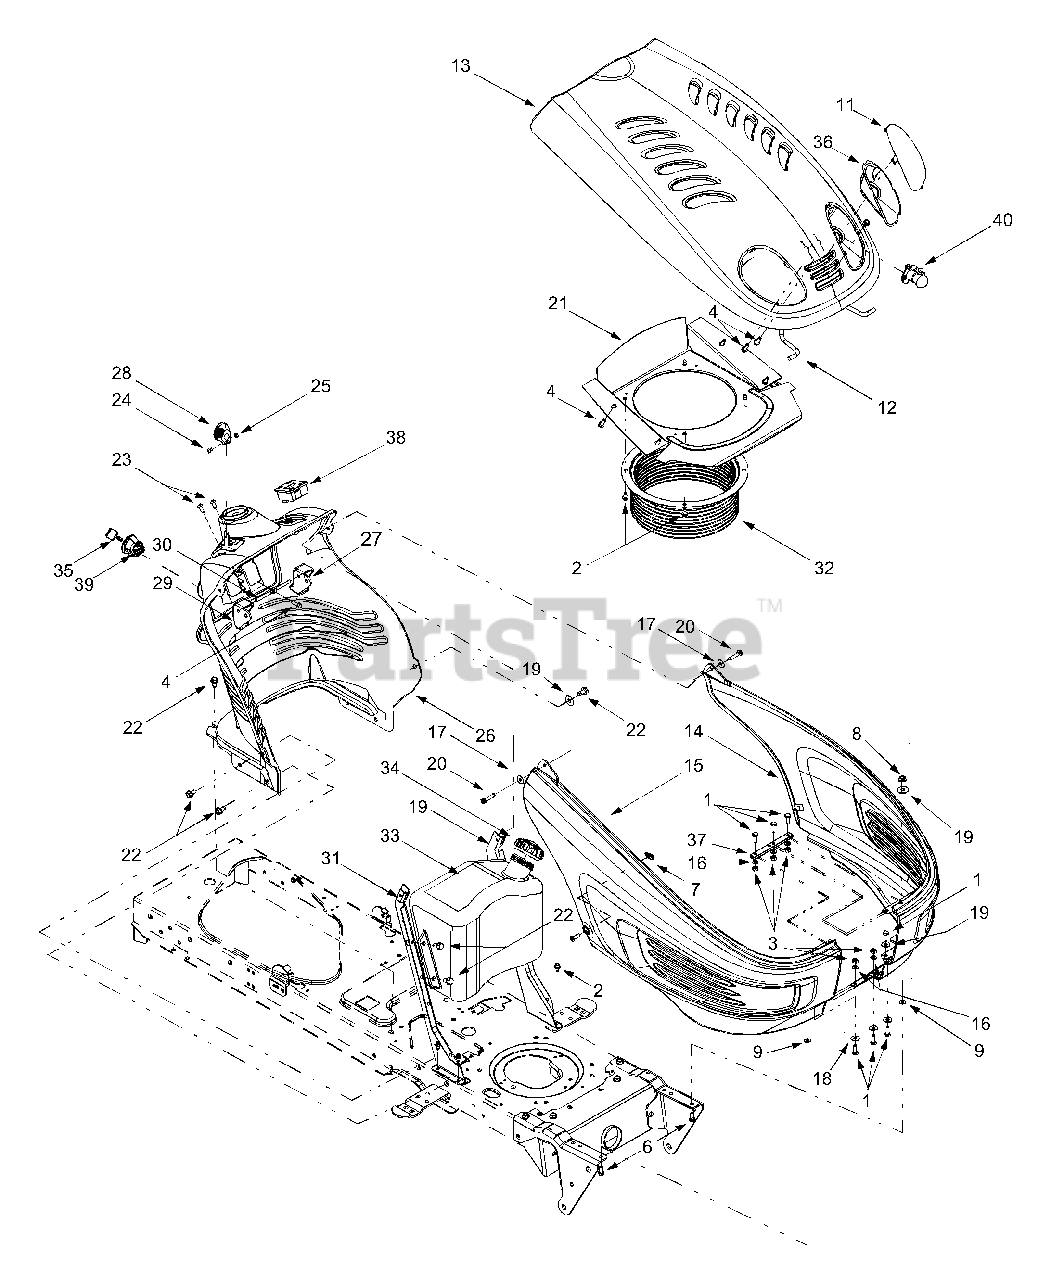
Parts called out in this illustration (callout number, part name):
1	Hex Cap Screw, 1/4-20 x .75
2	Self-tapping Screw, 1/4-20 x .5
3	Hex Nut, 1/4-20
4	Self-tapping Screw, 1/4-15 x .75
5	Pan Phillips Screw, 1/4-20 x .75
6	Hex Cap Screw, 5/16-18 x 1.25
7	U-type Speed Nut, 1/4-20
8	Hex Lock Nut, 5/16-18
9	Speed Nut
10	Hood Latch Rod
11	RH Head Light Lens
12	Hood Support Rod
13	Hood
14	LH Side Panel
15	RH Side Panel
16	Lock Washer, 1/4
17	Flat Washer, .283 x .75 x .030
18	Flat Washer, .28 x .74 x .063
20	Self-tapping Screw, 1/4-20 x 1.25
22	Self-tapping Screw, 5/16-18 x .75
23	Torx Self-tapping Screw, 1/4-14 x .625
24	Torx Screw, #8-32 x .375
25	Hex Nut, 8-32
26	Dash Panel (models w/ Manual PTO)
27	Parking Brake Button
28	Throttle Control Lever
29	Cruise Control Button
30	Brake/Cruise Pivot Rod
33	Fuel Tank, 2-gallon (Shown)
34	Fuel Cap
35	Ignition Key w/ plastic cover
36	Headlight Reflector
39	Ignition Switch
40	Headlight Assembly
